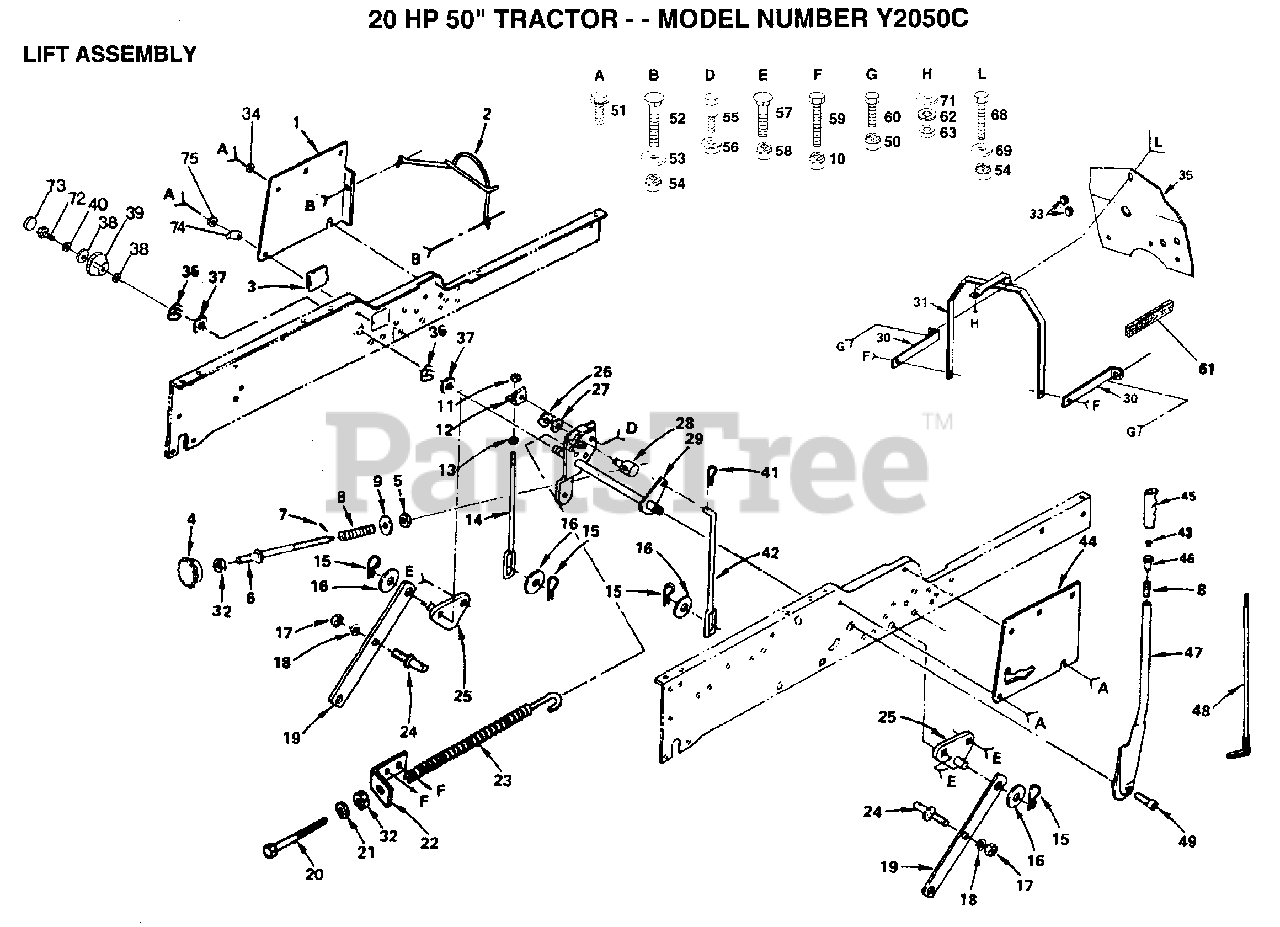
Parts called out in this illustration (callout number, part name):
2	"GUARD, BELT"
3	COVER ACCESS
4	KNOB INF 3/8-16
5	NUT T
6	ROD ADJ. T
8	SPRING T
9	WASHER
11	NUT
12	BRACKET T
13	NUT.HEX.3/8-16UNC
14	LINK-LIFT MOW T
15	SPRING H
17	NUT
18	LOCKWASHER
19	SUSPENSION ARM GT
20	BOLT-ADJ SPRING T
21	WASHER
24	PIVOT STUD GT
25	SUSP BRACKET T
26	KLIP RING
27	WASHER
28	TRUNION LT
29	SHAFT ASS'Y LIFT
30	BRACKET T
32	NUT
34	LOCKWASHER
35	"SHIELD HEAT, BASE"
36	E-RING
37	WASHER
38	WASHER
39	HEIGHT INDICATOR
40	LOCKWASHER
42	LIFT LINK RH T
45	GRIP HANDLE
48	LEVER ROD LT
49	"BOLT,HEX"
51	SCREW LT
52	BOLT
53	WASHER
55	SHOULDER BOLT T
56	NUT T
57	BOLT
58	LOCKNUT
59	BOLT
60	BOLT
61	FOAM STRIP T
68	BOLT
69	WASHER M
71	WASHER PM
73	"PLUG,HOLE"
74	POINTER HGT IND
75	WASHER T
